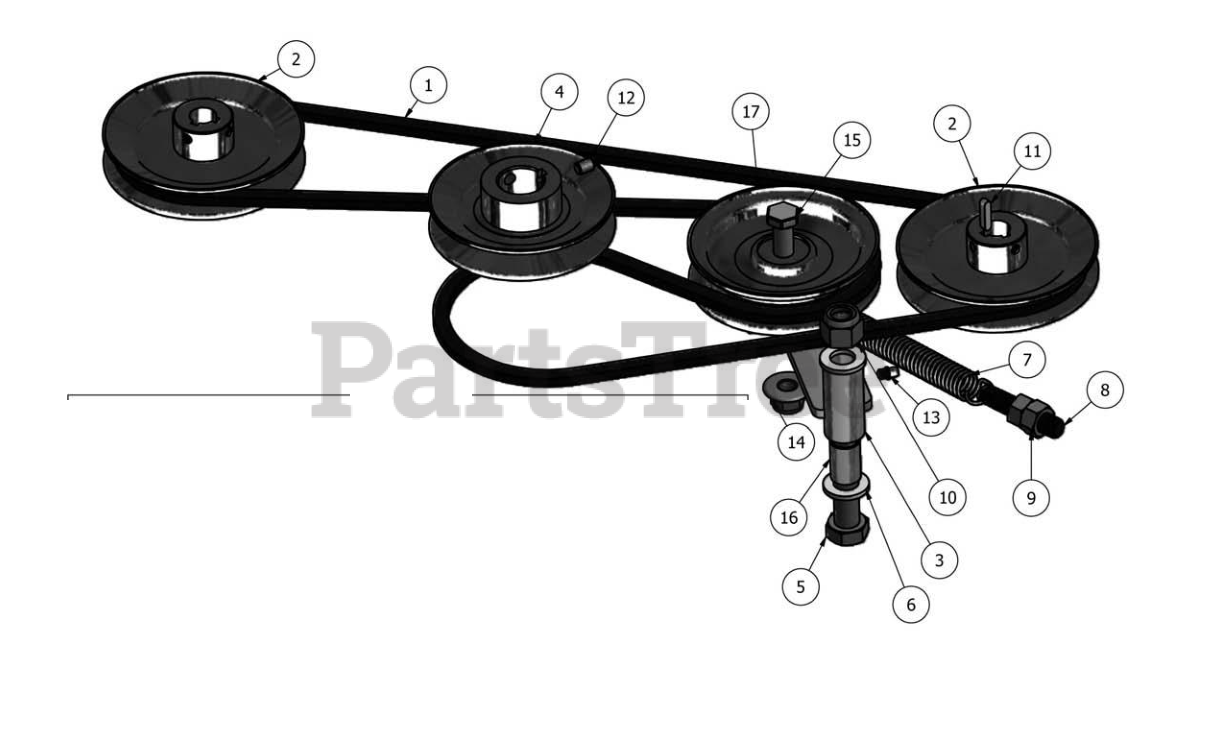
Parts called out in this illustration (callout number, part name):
2	5" Pump Pulley Cast 15mm
3	Pump Idler Braeket
4	4 3/4" Motor Pulley
5	5/8" x 4" Hex Bolt
6	.635 ID Plastic Washer
7	Pump Idler Spring
8	Spring Tensioner
9	1/2" Hex Nut
10	5/8 Nylock Nut
11	5mm x 1 Key
12	3/8" Set Screw
13	Grease Fitting (Drive-In Type)
14	1/2-13 Nylon Flange Nut
15	1/2-13x3 Hex Bolt
16	Brass Bushing 5/8 x 1 1/8
17	4 3/4" Idler Pulley
